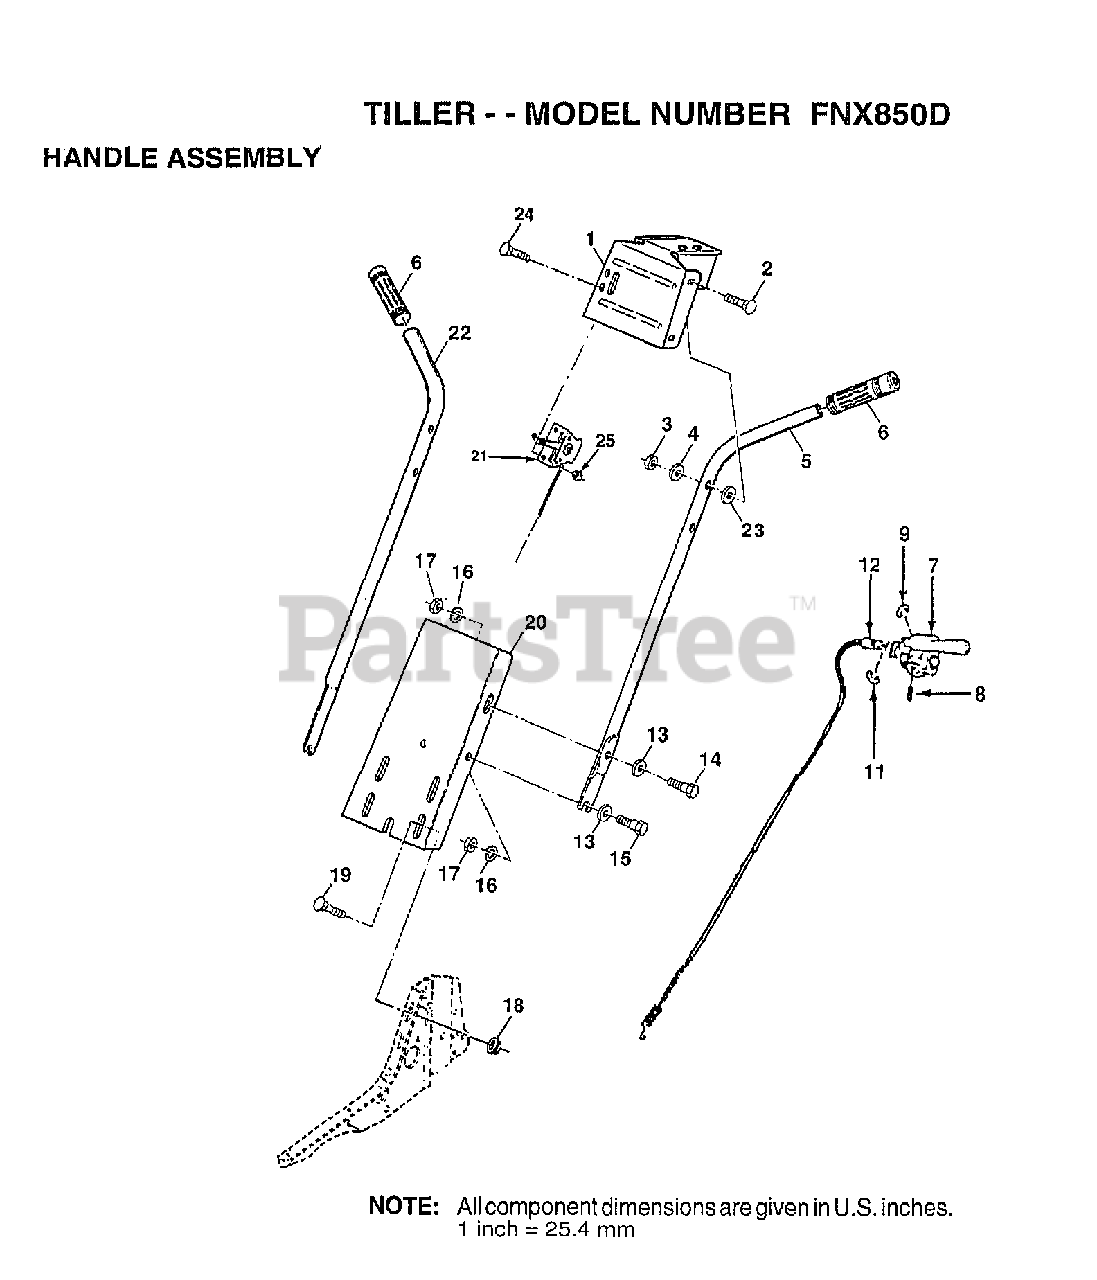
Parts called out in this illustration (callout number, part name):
2	BOLT
4	WASHER
5	HANDLE.LH
7	LEVER CONTRL TINE
8	"PIN PIVOT,GROOVED"
9	RETAINER RING
11	E-RING
12	CABLE CLUTCH T
13	WASHER
15	BOLT
16	LOCKWASHER
17	NUT.HEX.5/16-18
18	NUT
19	BOLT
20	PANEL. HANDLE
23	WASHER
24	SCREW.PNHD.10-24
